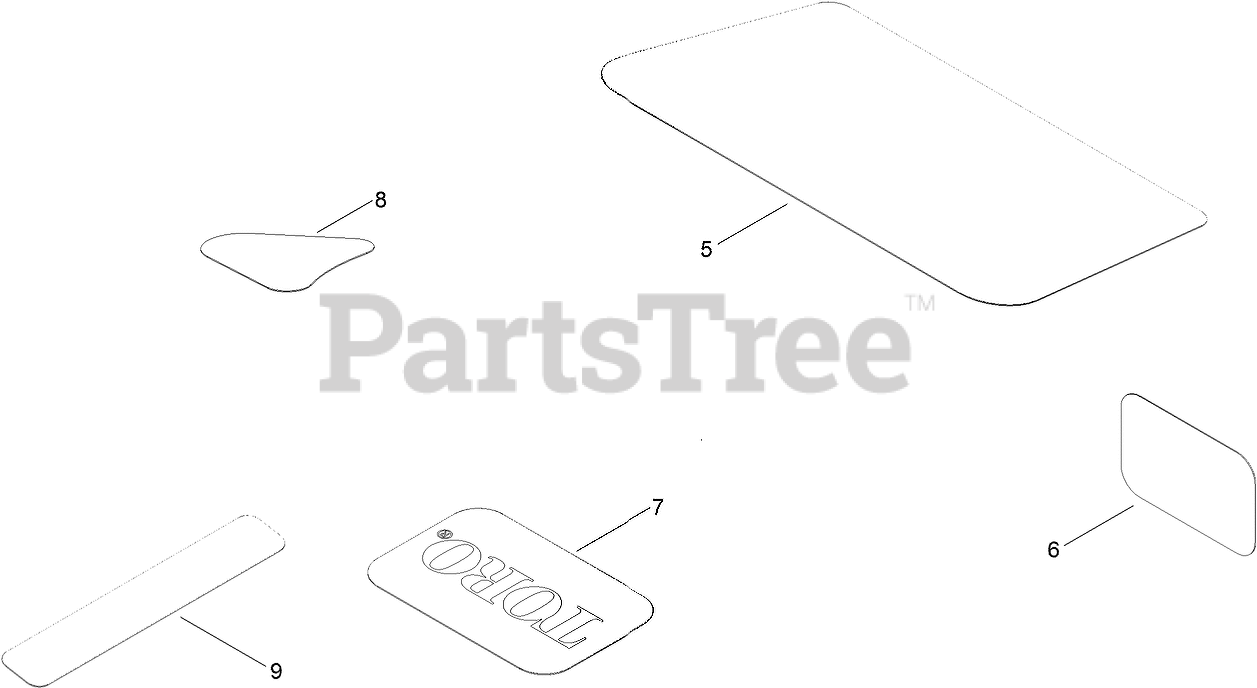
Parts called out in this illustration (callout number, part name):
5	DECAL-ENGINE
6	PLACARD-INTAKE
8	DECAL-DRAIN, OIL
9	DECAL-SHUTDOWN
